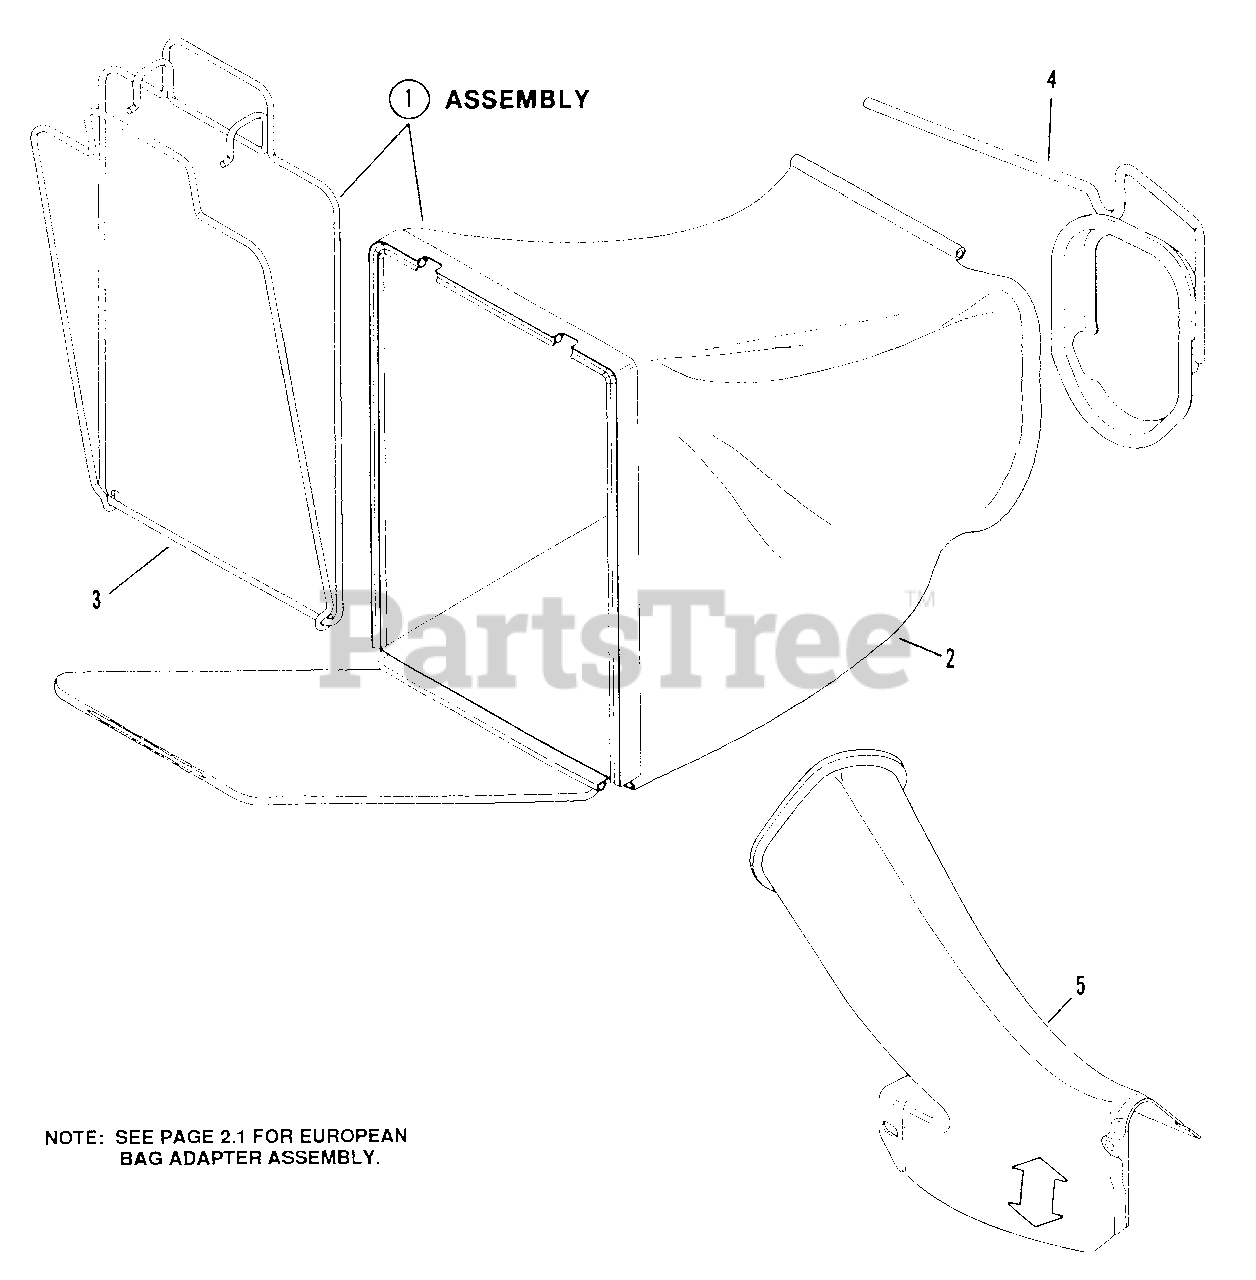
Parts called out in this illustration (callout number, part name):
1	ASSEMBLY, Grass Bag
2	BAG, Door Type
3	ASSEMBLY, Bag Wire
4	CONNECTOR, Grass Bag
5	ADAPTER, Bag
